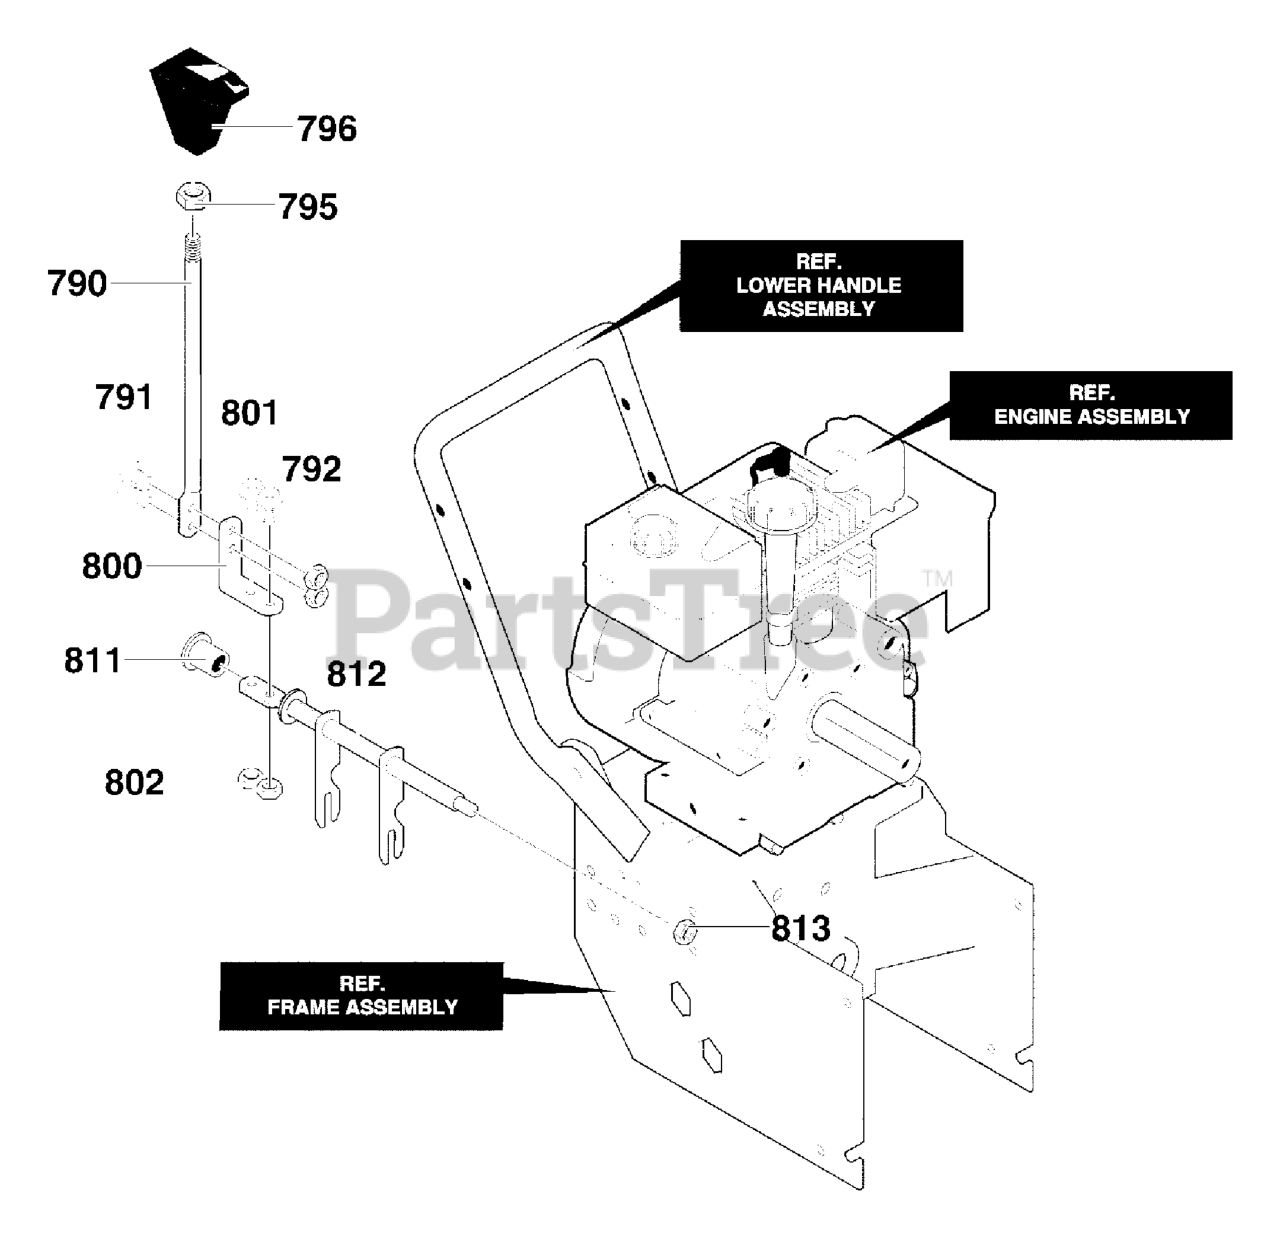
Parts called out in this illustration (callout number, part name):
790	ROD, SHIFT
791	SCREW, 1/4-20X.75
792	NUT, 1/4-20 REGHEXCTRLK
795	NUT, 1/2-13 HEXJAM
796	KNOB, SHIFT
800	LEVER, SPRING SHIFT
801	SCREW, 1/4-20X.75
802	NUT, 1/4-20 REGHEXCTRLK
811	BEARING, FLANGED
812	ROD, ASSY. YOKE
813	NUT, 3/8-16 HEXCTRLK
